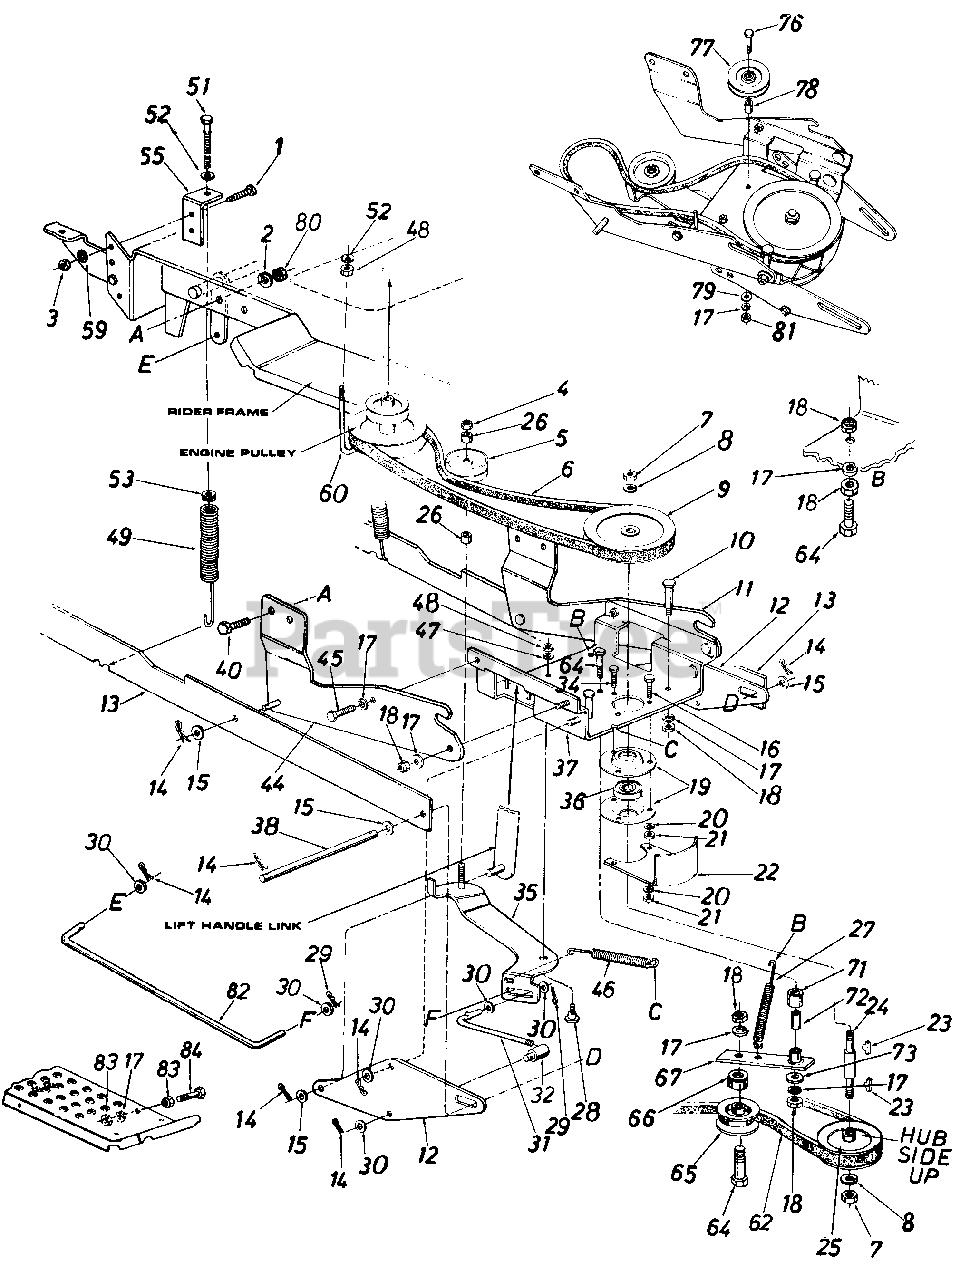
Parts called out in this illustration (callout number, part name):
1	Hex Bolt 1/4-28 x 1.00" Lg. Grade 5
2	L.Wash. 1/4" I.D.*
3	Hex Nut 1/4-28 Thd.*
4	Hex Cent. L-Nut 3/8-16 Thd.
5	Idler Pulley
6	"V" Belt
7	Hex Jam Nut 5/8-11 Thd
8	L.Wash. 5/8" I.D.*
9	6.50" O.D. x 5/8 Pulley
10	Shoulder Bolt
11	Channel Support Brkt.R.H.
12	Linkage Brkt.
13	Linkage Arm Ass'y.
14	Intern. Coter Pin .50 Dia.*
15	Fl.Wash.
16	Hex Bolt 5/16 x 1.25" Lg.
17	L.Wash. 3/8" I.D.*
18	Hex Jam Nut 3/8-16 Thd.
19	Bearing Housing
20	L.Wash. 5/16" I.D.*
21	Hex Nut 5/16-18 Thd.*
24	Pulley Spindle
25	5/8 Pulley-6.28 I.D. x 5.56 O.D.
26	Spacer .383 I.D. x .503 O.D. x .562 Lg.
27	Extension Spring .54 O.D. x 5.25"
28	Shoulder Bolt
29	Coter Pin 3/32" Dia.
30	Fl.Wash.
31	Control Rod
32	Ferrule
34	Hex Sems Scr. 5/16-18 x .75" Lg.*
35	Clutch Idler Brkt. Ass'y.
36	Ball Bearing
37	Channel Ass'y.
38	Lift Handle Shaft
40	Hex Self-Tap Scr. 1/4-20 x .75" Lg.
44	Channel Supporting Brkt.-L.H.
45	Hex Bolt 3/8-16 x 1.0" Lg.*
46	Extension spring
47	L.Wash. 5/16" I.D.
48	Hex Nut 5/16-18 Thd.*
49	Helper Spring
51	Hex Scr. 5/16-18 x 2.0" Lg. Special
52	Bell Wash. .345 I.D. x .88 O.D. x .06
53	Spring Insert
60	J.Bolt 5/16-18 Thd.
62	"V"Belt 1/2 "A" x .89" Lg.
64	Hex Bolt 3/8-16 x 2.0" Lg.*
65	Idler Pulley
66	Spacer .385 I.D. x .503 O.D. x .562" Lg.
67	Idler Arm Ass'y.
71	Spacer.380" I.D.
72	Spacer .3775 I.D. x .60 O.D. x 8.3 Lg.
73	Fl.Wash. 3/8 I.D. x 1" O.D. x 1.27
76	Hex Bolt 3/8-16 x 2.5" Lg. (Grade 5)
77	Idler Pulley .38 I.D. x 3.06 O.D.
78	Spacer .385 I.D. x .630 O.D. x .76 Lg.
79	Fl.Wash. .39 I.D. x 1-3/4 O.D. x 3/16"
80	Hex L-Nut 1/4-20 Thd.
81	Hex Nut 3/8-16 Thd.*
82	Clutch Control Rod
83	Hex Nut 3/8-24 Thd.*
84	Hex Bolt 3/8-24 x 2.25" Lg.*
